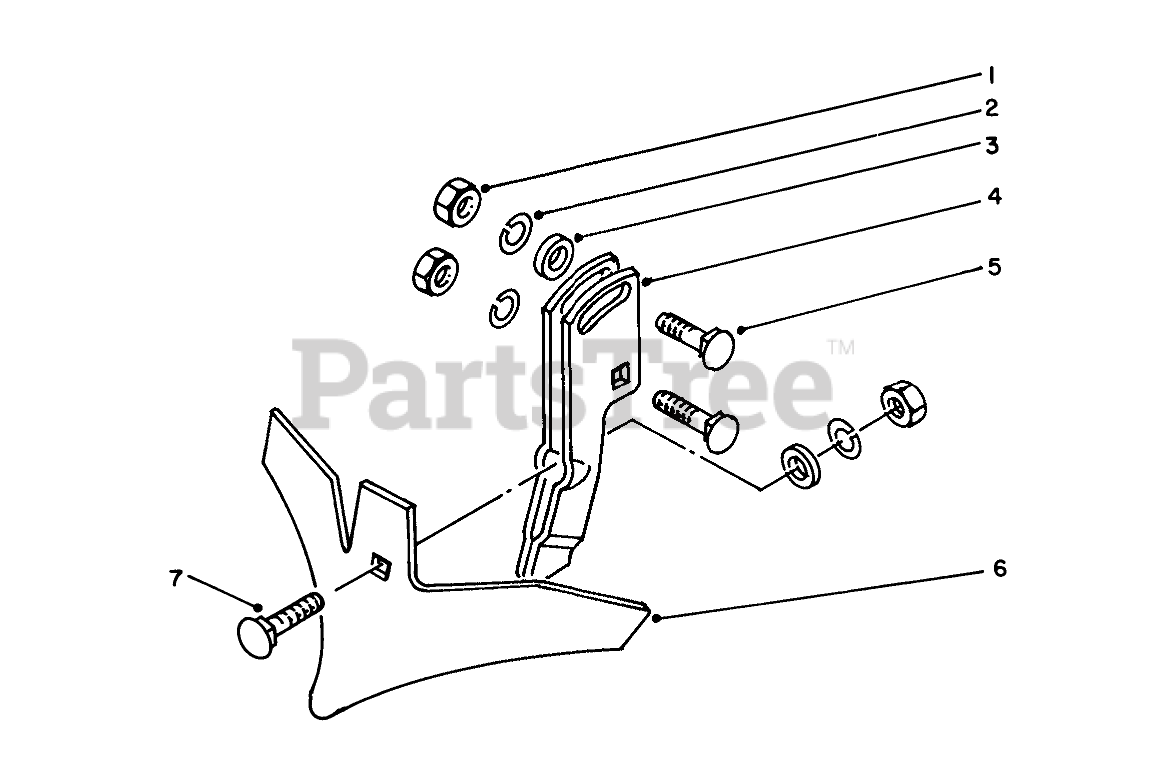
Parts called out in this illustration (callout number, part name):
1	NUT-HEX
2	WASHER-LOCK
3	WASHER-FLAT
4	Holder
5	BOLT-CARR
6	15" Sweep
7	Plow Bolt
